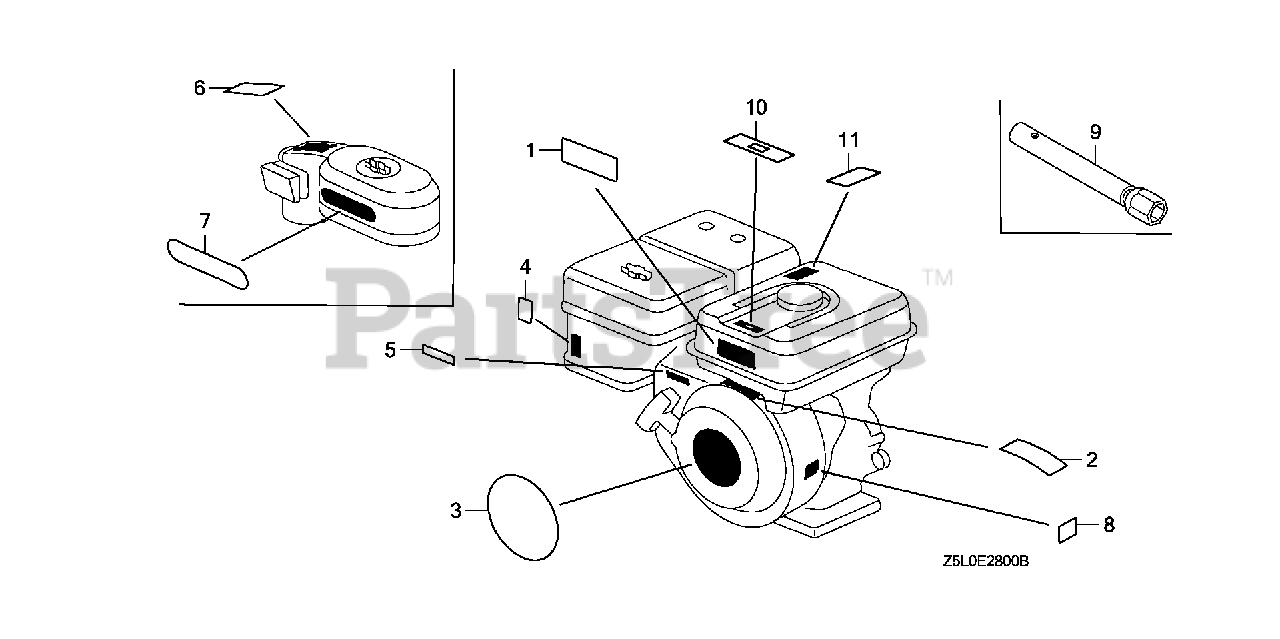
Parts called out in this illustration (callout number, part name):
2	MARK, OPERATOR CAUTION (ENGLISH)(MADE IN JAPAN)
3	EMBLEM (GX340)
8	MARK, OIL CAUTION
